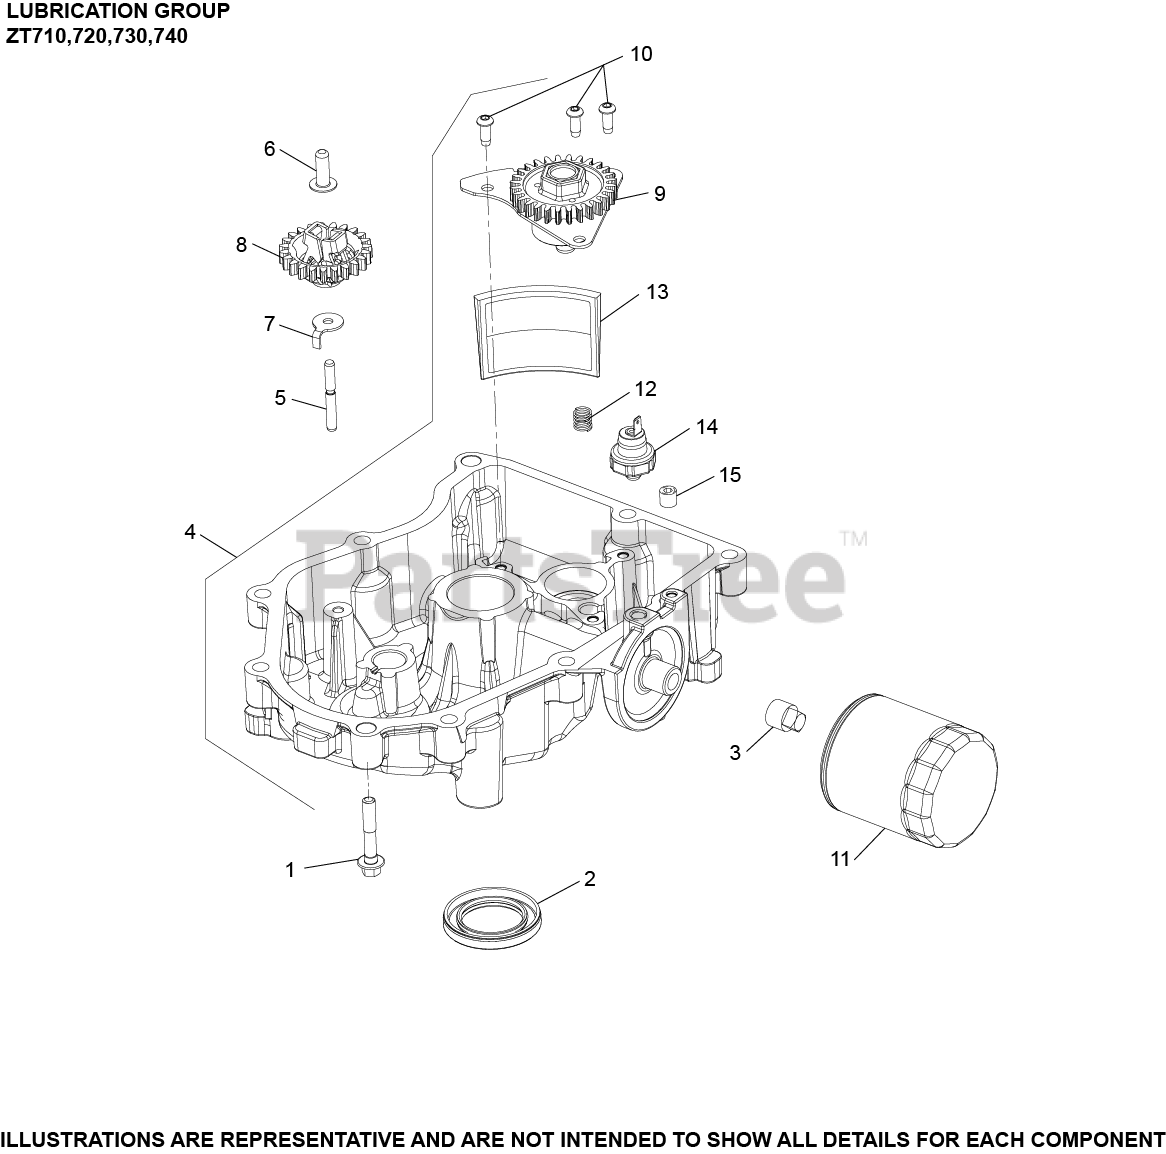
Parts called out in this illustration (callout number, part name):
1	SCREW, FLG M8X1.25X45
2	SEAL, OIL
3	PLUG, SQ HD PIPE 3/8"
4	PAN ASSEMBLY, OIL
5	SHAFT, GOVERNOR GEAR
6	PIN, GOVERNOR REGULATING
7	TAB, LOCKING
8	KIT, GOVERNOR GEAR
9	PUMP ASSEMBLY, OIL
10	SCREW, BUTTON HEAD
11	OIL FILTER
12	SPRING, COMPRESSION
13	SCREEN, OIL
15	PLUG, CTSK PIPE 1/8"
